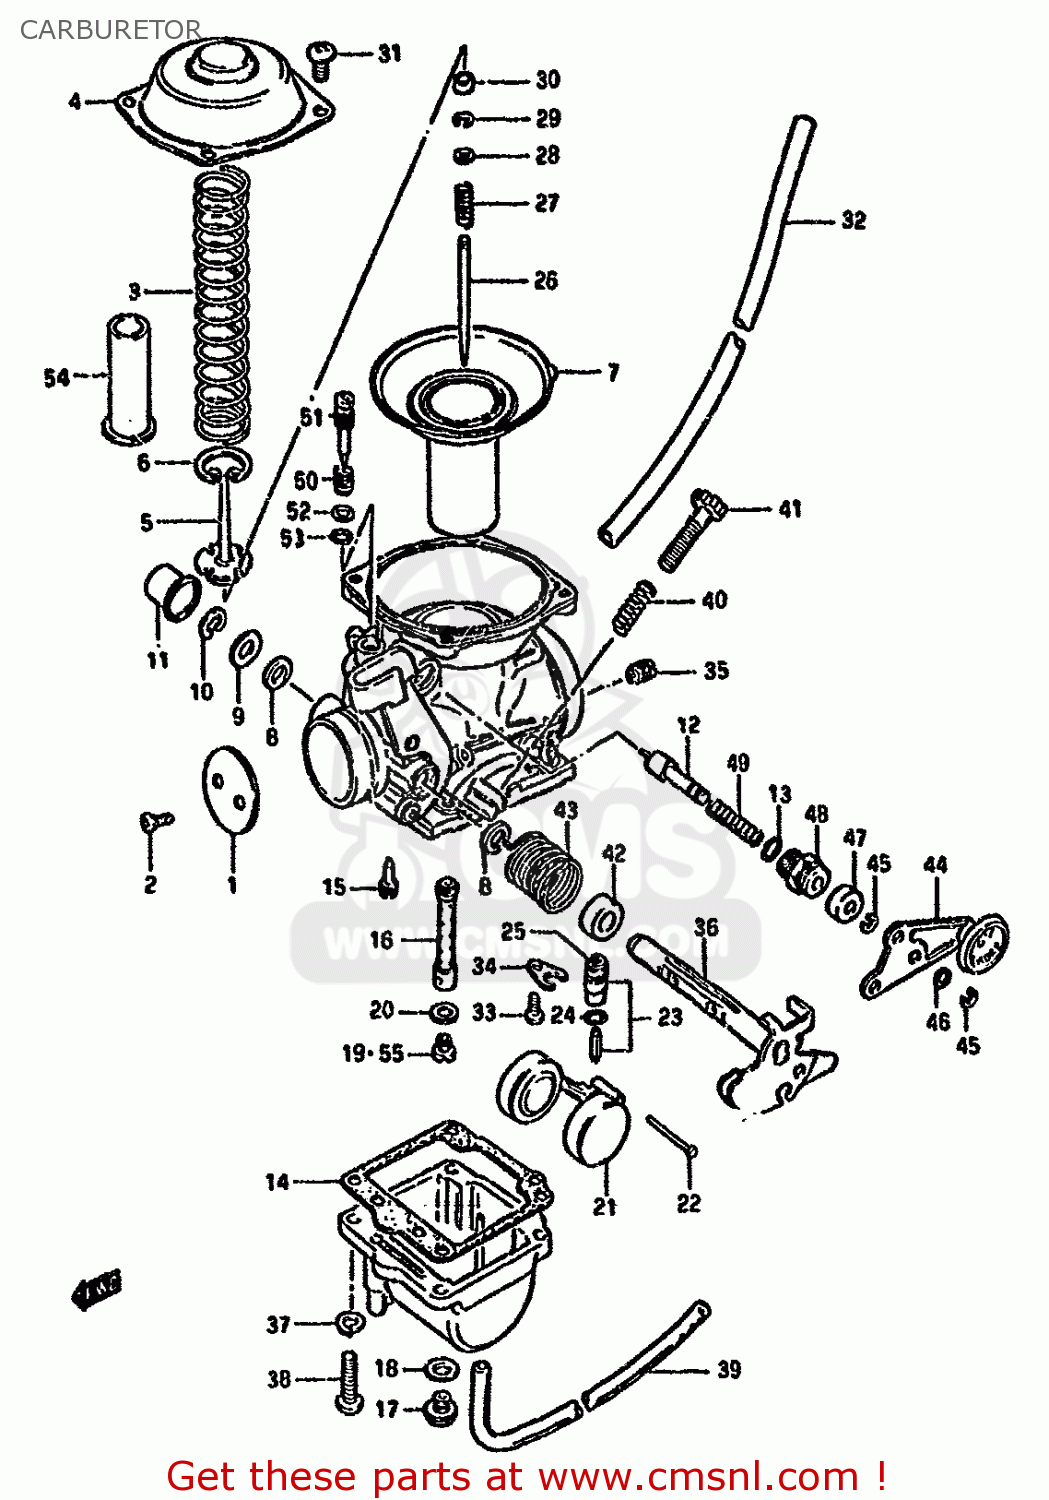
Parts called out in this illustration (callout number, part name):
1	THROTTLE VALVE (100)
2	SCREW
3	SPRING
4	COVER
5	HOLDER,GUIDE
6	E RING
7	DIAPHRAGM ASSY
8	SEAL
9	GASKET,THROTTLE SHAFT (NAS)
10	E RING
11	CAP
12	PLUNGER ASSY
13	O RING
14	GASKET,FLOAT CHAMBER (NAS)
15	JET,PILOT(42.5)
16	JET,NEEDLE(P-1)
17	PLUG,DRAIN
18	GASKET (NAS)
19	JET,MAIN(130)
20	WASHER,NEEDLE NOZZLE
21	FLOAT
22	PIN,FLOAT
23	VALVE ASSEMBLY,NEEDLE
24	O-RING,NEEDLE VALVE
25	FILTER
26	NEEDLE,JET
27	SPRING
28	WASHER
29	CLIP
30	RING
31	SCREW 5X10
32	HOSE
33	SCREW
34	PLATE
35	JET,AIR(150)
36	SHAFT ASSEMBLY,THROTTLE
37	LOCK WASHER
38	SCREW
39	HOSE
40	SPRING,THROTTLE ADJUST
41	SCREW,THROTTLE STOP
42	RING
43	SPRING,THROTTLE SHAFT
44	STARTER LEVER ASSY
45	E RING
46	WASHER
47	CAP,STARTER VALVE
48	GUIDE SCREW,PLUNGER
49	SPRING
50	SPRING
51	SCREW,PILOT AIR
52	WASHER
53	O RING,PILOT AIR SCREW
54	RING
55	JET,MAIN(127.5)
